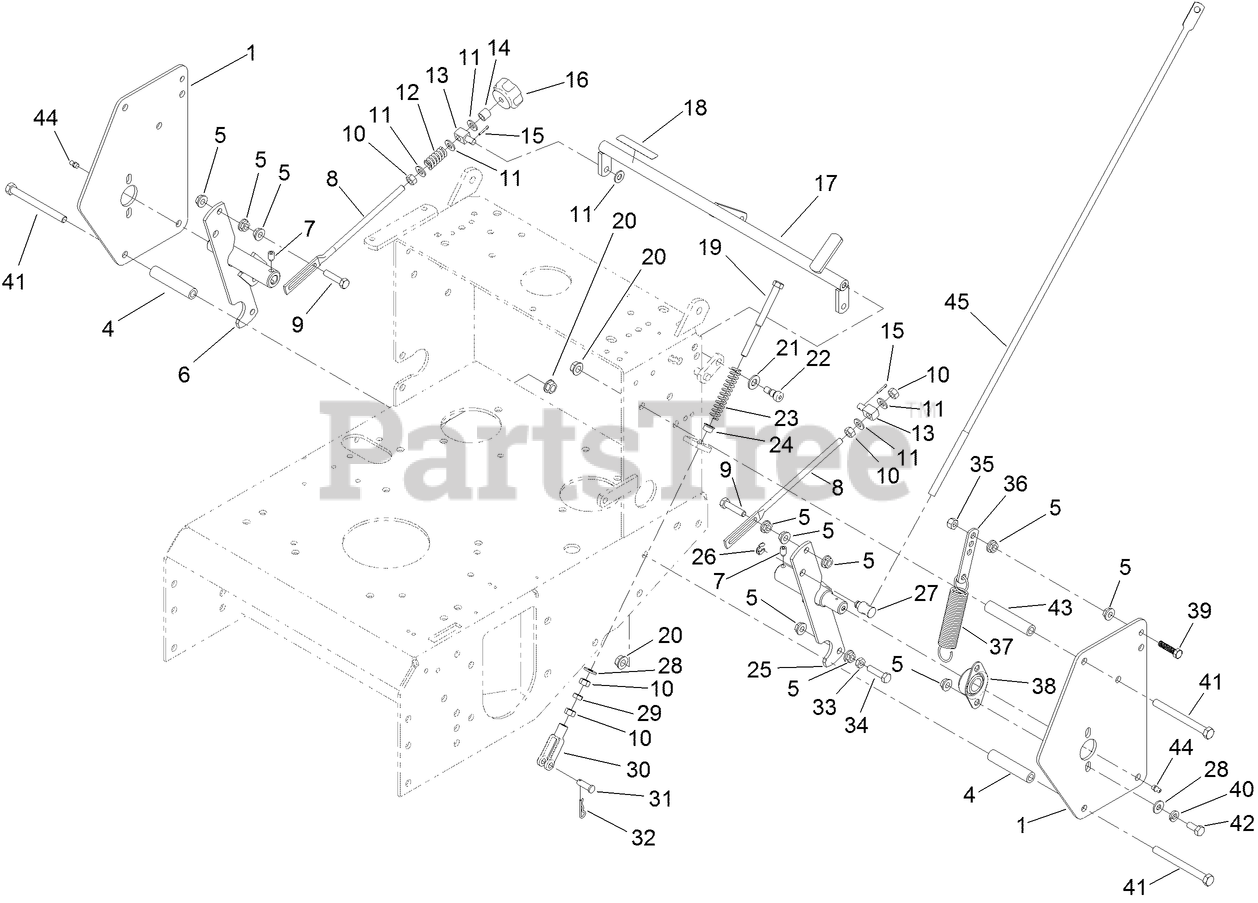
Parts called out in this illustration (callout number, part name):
1	SHIELD-CONTROL
4	SPACER-SHIELD
5	NUT-HF
6	SHAFT-CONTROL, RH
7	SCREW-SET
8	LINK-CONTROL, SPEED
9	SCREW-HH
10	NUT-HEX
11	WASHER-PLAIN
12	SPRING-COMPRESSION
14	SPACER
15	PIN-COTTER
16	KNOB-TRACKING
17	CRANK-CONTROL, SPEED
18	DECAL-TRACKING
19	BOLT-RETURN, NEUTRAL
20	NUT-HHF, WHIZ
21	WASHER-FLAT
22	SCREW-HSH
23	SPRING-RETURN, NEUTRAL
24	BUSHING-FLANGED
25	SHAFT-CONTROL, LH
26	RING-RETAINING
27	SWIVEL-LEVER, DRIVE
28	WASHER-FLAT
29	NUT-JAM
30	YOKE-ADJUSTABLE
31	PIN-CLEVIS
32	PIN-COTTER
33	NUT-JAM
34	SCREW-HH, SPECIAL
35	NUT-LOCK, NI
36	TAB-SPRING, EXTENSION
37	SPRING-EXTENSION
38	BEARING-FLANGE, SIDE
39	BOLT-TAP, HH
40	WASHER-LOCK
41	SCREW-HH
42	SCREW-HH
43	SPACER-SHIELD
44	FITTING-GREASE
45	ROD-LEVER, DRIVE
